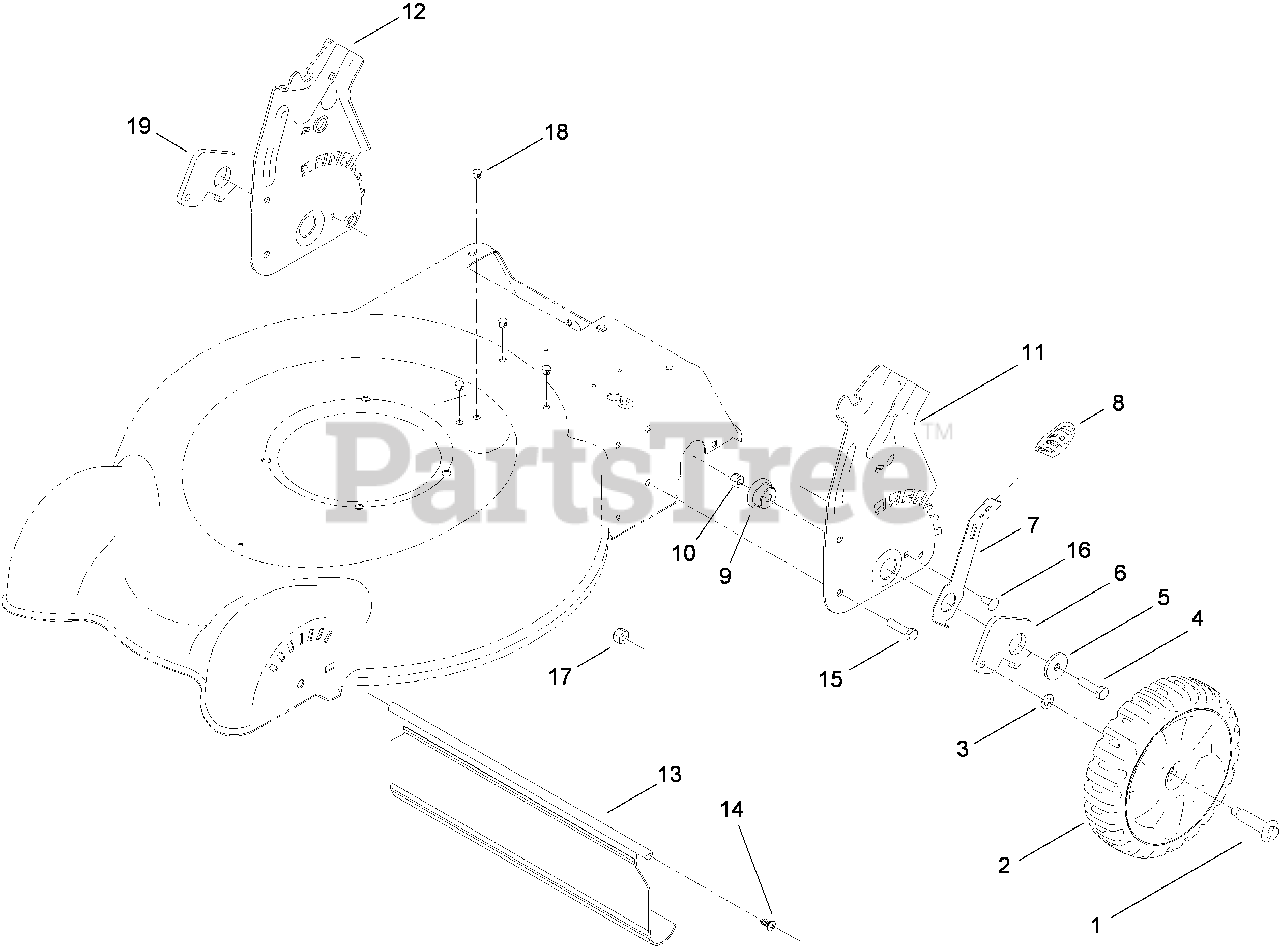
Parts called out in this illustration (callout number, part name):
1	BOLT-SHOULDER
2	8 INCH WHEEL AND TIRE ASM
4	SCREW-HH
5	Washer-Flat
6	Arm-Pivot, Rear (LH)
7	Arm-Spring
8	Knob-Lever, HOC
9	Bushing-Mount, HOC
10	NUT-LOCK, NI
11	PLATE-HOC, LH
12	PLATE-HOC, RH
13	SHIELD-TRAILING
14	SCREW-PTH
15	SCREW-HH
16	SCREW-CARR
17	NUT-LOCK, NI
18	Plug-Dome
19	ARM-PIVOT, REAR (RH)
